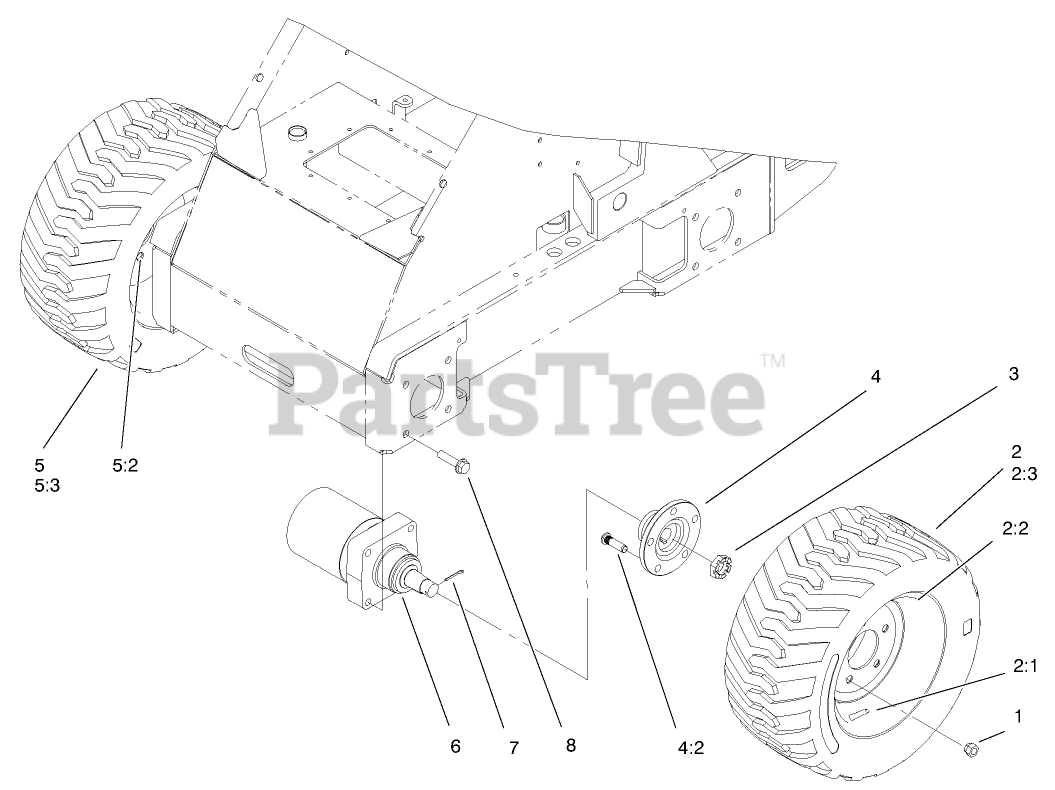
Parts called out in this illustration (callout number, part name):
1	NUT-LUG
2	LH WHEEL AND TIRE ASM
2:1	STEM-VALVE
2:2	WHEEL
4	HUB ASM
4:2	STUD-TYPE, DRIVE
5	RH WHEEL AND TIRE ASM
5:2	WHEEL
6	HYD MOTOR ASM
7	PIN-COTTER
8	SCREW-HHF
